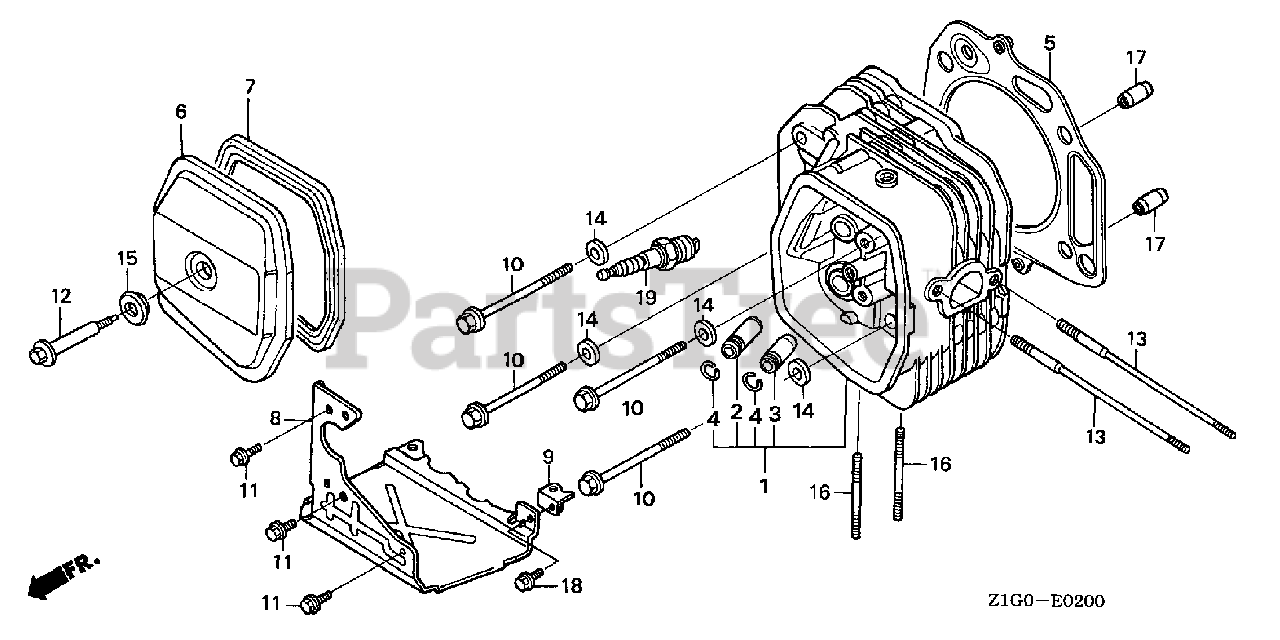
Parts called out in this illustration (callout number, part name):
1	CYLINDER HEAD
2	GUIDE, VALVE (OVER SIZE)
3	GUIDE, EX. VALVE (OVER SIZE)
4	CLIP, VALVE GUIDE
5	GASKET, CYLINDER HEAD
6	COVER, HEAD
7	GASKET, HEAD COVER
8	COVER (LOWER)
9	STAY, COVER (LOWER)
10	BOLT, FLANGE (10X85)
11	BOLT, FLANGE (6X12) (CT200)
12	BOLT, HEAD COVER
13	BOLT, STUD (8X131.5)
14	WASHER, PLAIN (10MM)
15	WASHER, HEAD COVER
16	BOLT, STUD (8X32)
17	PIN, DOWEL (12X20)
18	BOLT, FLANGE (6X12)
19	SPARK PLUG (BPR5ES) (NGK)
